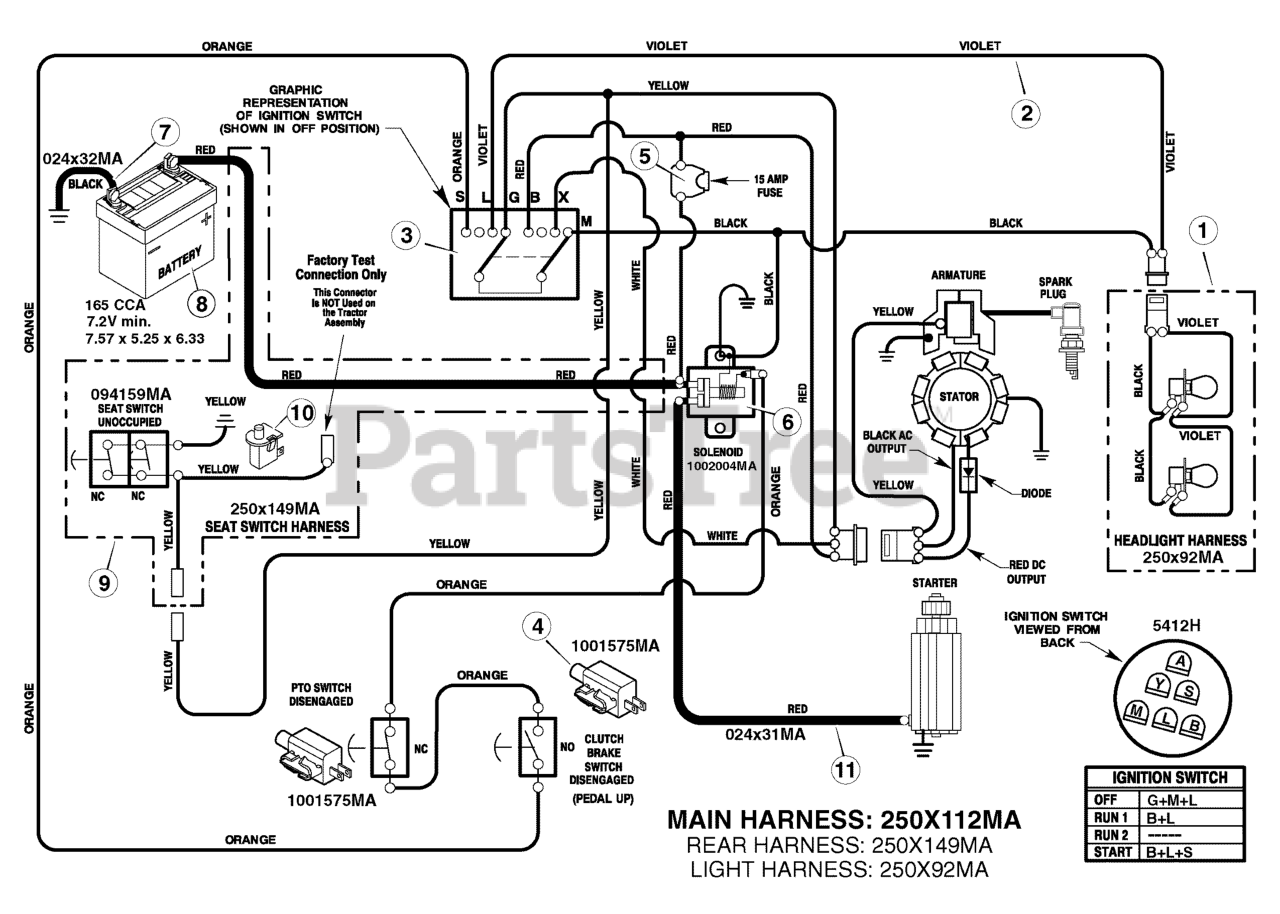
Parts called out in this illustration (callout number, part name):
1	Harness, Light Wire
2	Harness, Chassis Wire
3	Switch, Ignition
4	Switch, Limit
6	Solenoid
7	Cable, Battery Ground
9	Harness, Seat Switch Wire
10	Switch, Seat Sensor
